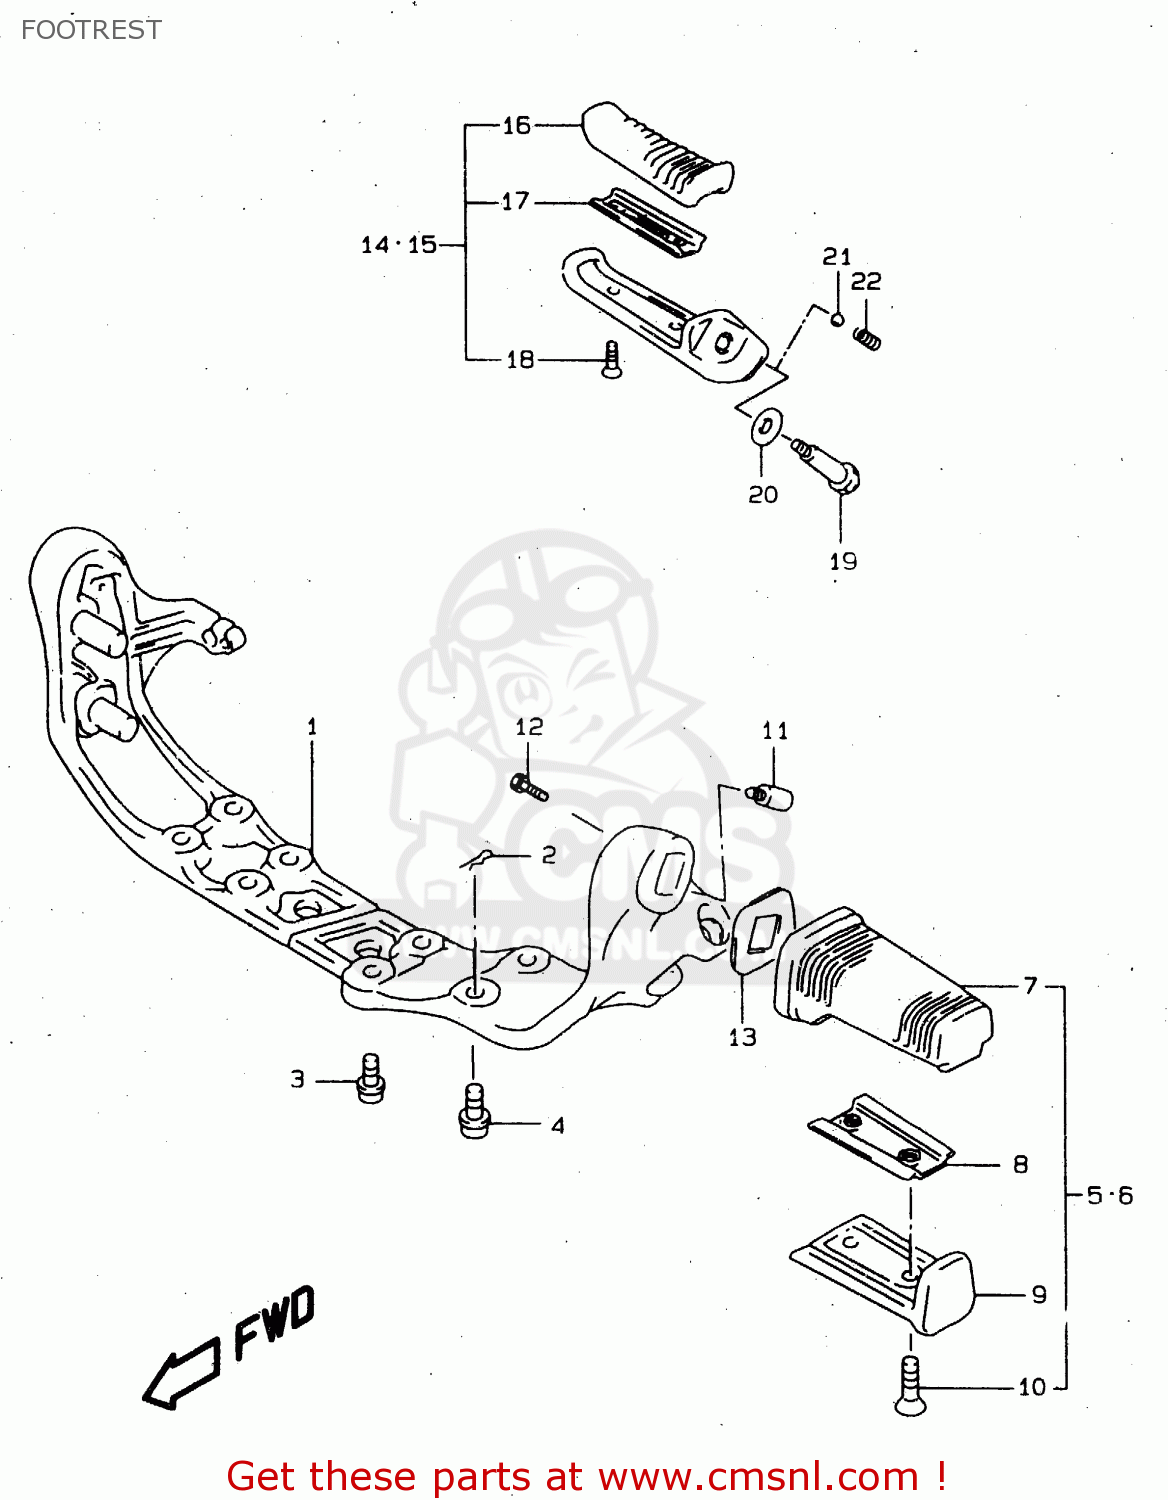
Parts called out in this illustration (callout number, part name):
1	BRACKET,FR FOOTREST
2	SNAP
3	BOLT
4	BOLT(8X25)
5	FOOTREST ASSY,FR,R
6	FOOTREST ASSY,FR,L
7	RUBBER,FR FOOTREST
8	PLATE,RUBBER STOPPER
9	COVER,FR FOOTREST
10	SCREW(5X20)
11	BOLT,FRONT FOOTREST
12	SCREW
13	WASHER,FR FOOTREST
14	FOOTREST ASSY RH
15	FOOTREST ASSY PILLION LH
16	RUBBER,PILLION FOOTREST
17	PLATE,RUBBER STOPPER
18	SCREW(5X16)
19	BOLT(6X34.5)
20	SHIM
21	BALL
22	SPRING
